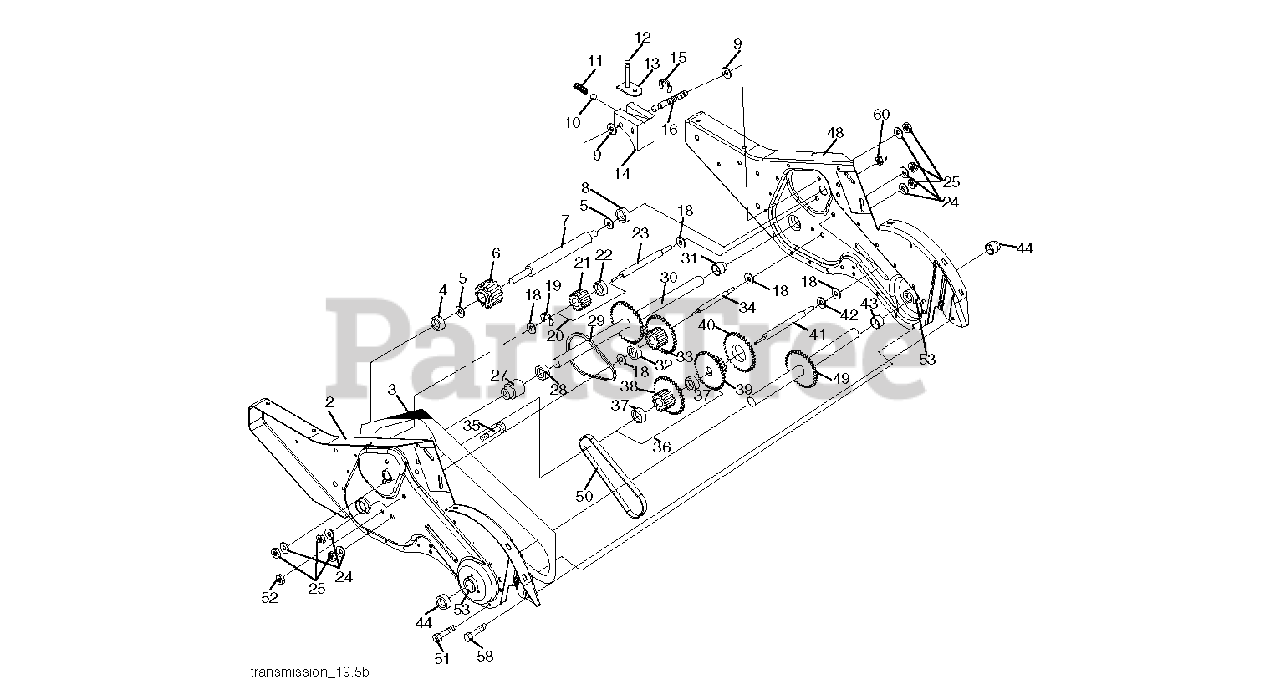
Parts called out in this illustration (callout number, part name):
1	TRANSMISSION ASM.
2	GEARCASE.ASM.CRT.LH.W/BEARING
3	GASKET
4	NEEDLE BRNG LT
5	THRUST WASHER
6	GEAR.PINION.INPUT
7	SHAFT.INPUT."D".TILLER
8	BEARING TI
9	WASHER, SEAL
10	STEEL BALL KIT
11	SPRING-SHIFT CRT
12	O-RING TI
13	SHIFTING ARM
14	SHIFT FORK TI
15	KLIP RING
16	SHAFT.SHIFTER.TILLER
19	KLIP RING
20	GEAR ASSY CRT
21	GEAR-REV IDLR CRT
22	NEEDLE BEARING TI
23	SHAFT CRT
24	LOCKWASHER
27	BEARING, SHAFT LH CRT
29	CHAIN CRT
30	GROUND SHAFT ASS'Y
31	BEARING, SHAFT RH CRT
32	SPACER TI
33	SPRCKT 8 GEAR CRT
34	SHAFT.SECONDARY.REDUCTION.CRT
35	SCRW WHIZ LOK CRT
36	SPROCKET ASS'Y W/BRG
37	BEARING
38	SPROCKET, TINE
39	GEAR TI
41	SHAFT.REDUCTION.TILLER
42	BRNG RACE T
43	SPACER TI
44	SEAL ASM, OIL
48	GEARCASE.ASM.CRT.RH.W/BEARING
49	TINE SHAFT
50	CHAIN.TILLER
51	SCREW
53	BEARING KIT
58	BOLT SHOULDER 1/4-20 UNC X.875
60	FITTING.GREASE.TAPERED
